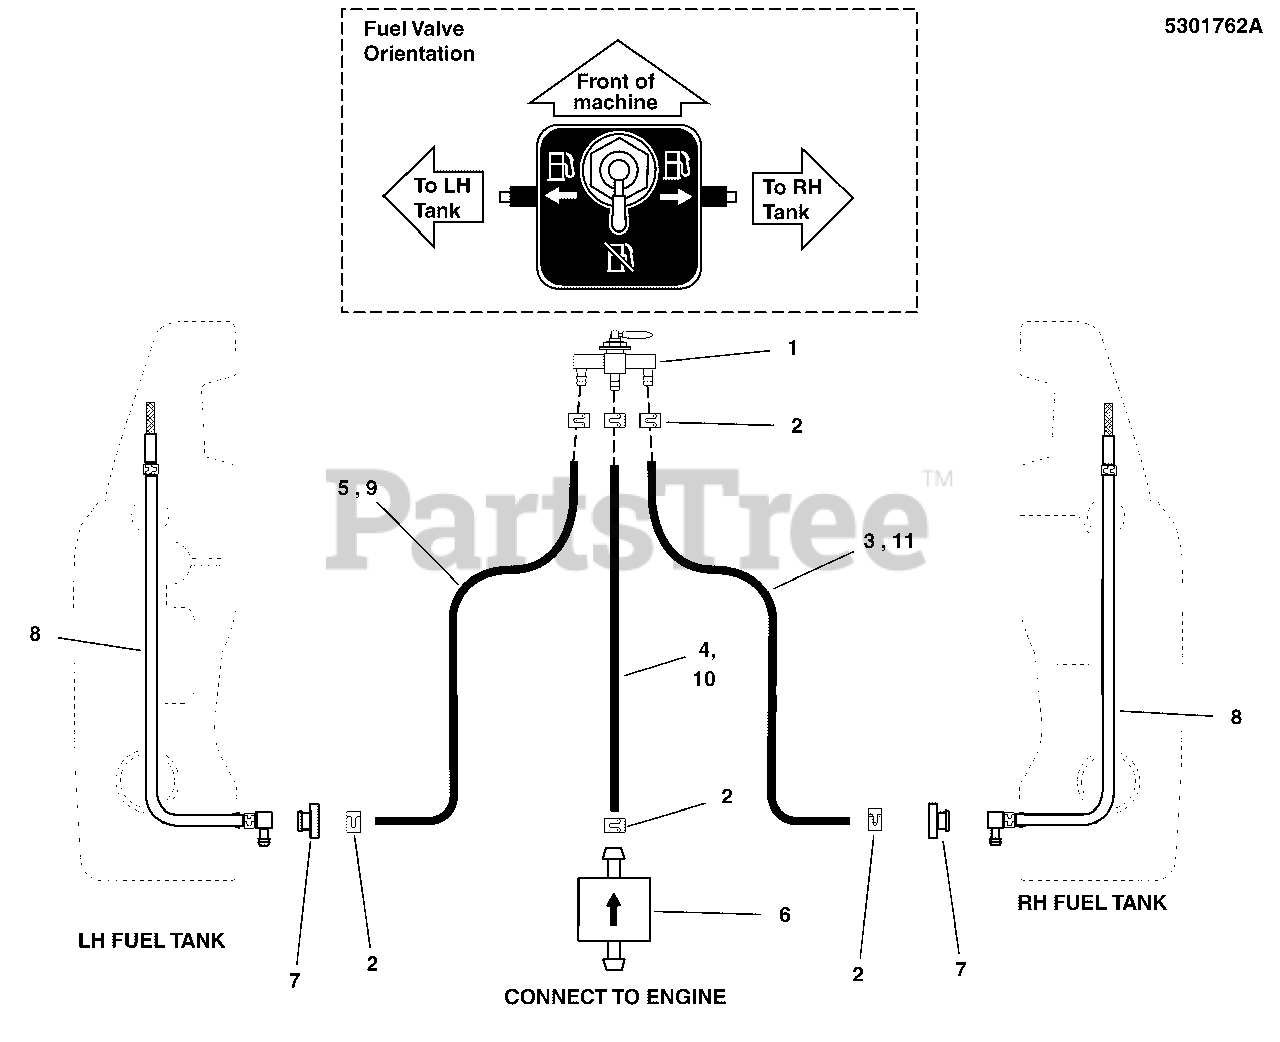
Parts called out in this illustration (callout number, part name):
1	VALVE, FUEL SHUT-OFF, 11772
2	CLAMP, HOSE, EXTERNAL, 1/2 - RED
3	HOSE, 1/4" FUEL, 22.00"
4	HOSE, 1/4" FUEL, 42.00"
5	HOSE, 1/4" FUEL, 54.00"
6	FUEL FILTER (SV)
7	BUSHING-FUEL TANK (SV)
8	PICKUP TUBE ASSEMBLY (SV)
9	HOSE, 1/4" FUEL, 22.00"
10	HOSE, 1/4" FUEL, 22.00"
11	HOSE, 1/4" FUEL, 52.00"
